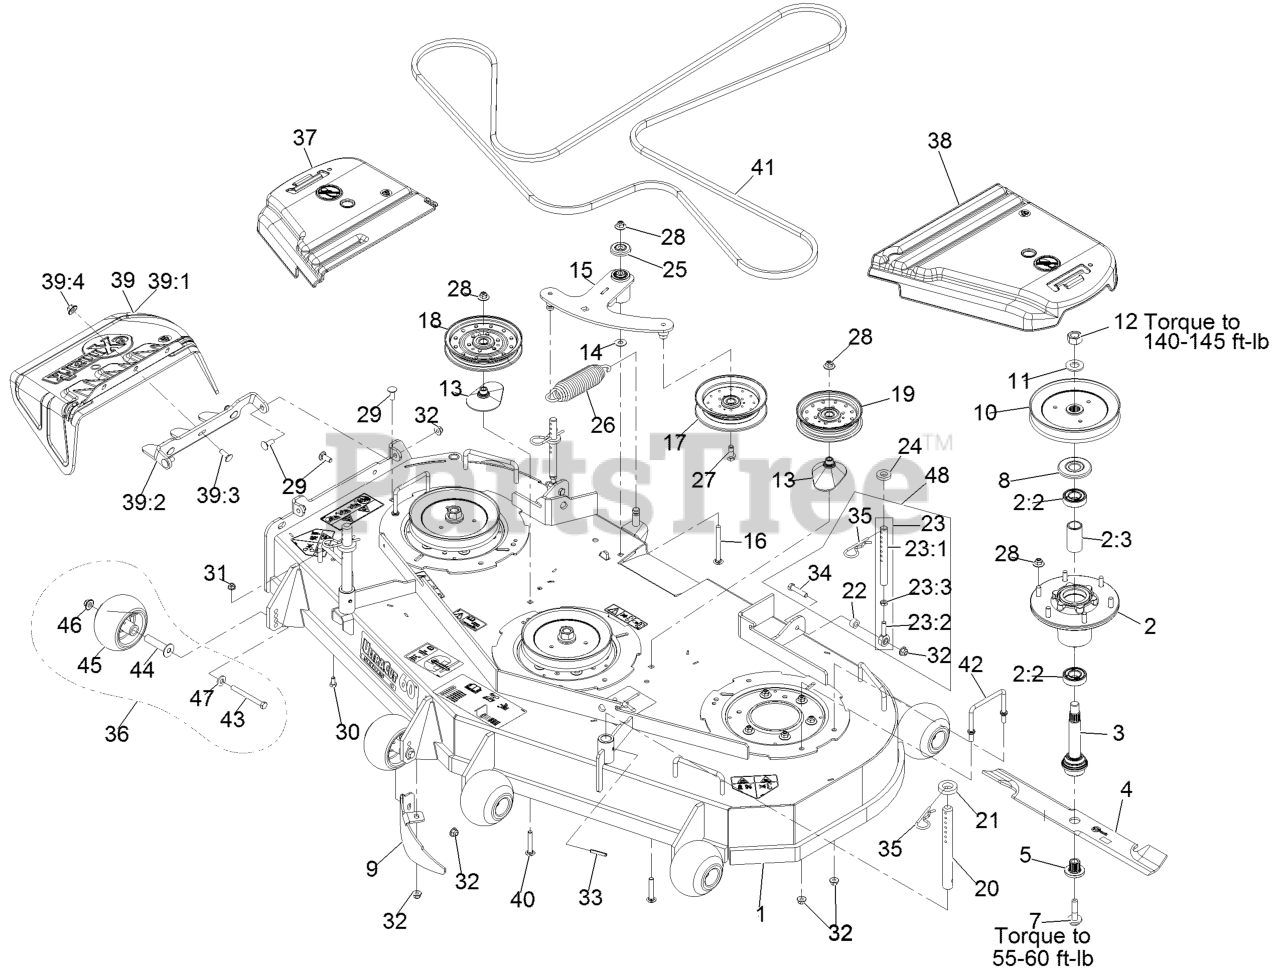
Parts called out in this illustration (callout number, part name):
1	ASM, DECK W/ DECALS, 60"
2	ASM-CUTTER HSG WITH BEARINGS
2:2	BEARING-BALL
2:3	SPACER-BEARING
3	ASM-SPINDLE AND SEAL
5	BUSHING,SPLINED
7	SCREW,SEMS 1/2-20 X 2.19
8	GUARD,BEARING TOP .989
9	DOGLEG - LZ60
10	SHEAVE,BLADE DRIVE 7.25
12	NUT-HEX
13	SPACER-PULLEY
14	WASHER-FLAT
15	ASM, DECK IDLER
16	SCREW-CARR
20	ROD,DECK SUPPORT
21	SPACER-DECK SUPPORT
23:1	LINK,SUPPORT
23:2	BALLJOINT
23:3	NUT-HJ
25	GUARD-TOP
26	SPRING-EXTENSION
27	SCREW-HFH
28	Nut-Nyloc 3/8-16 Flg
29	SCREW-CARR
30	SCREW-HH
31	NUT-HF, NI
32	NUT-HF, NI
34	SCREW-HH
35	PIN,HAIR COTTER
36	KIT, ANTI-SCALP ROLLER
37	COVER-BELT, RH
38	COVER-BELT, LH
39	ASM,DISCHARGE CHUTE
39:1	CHUTE,DISCHARGE
39:2	BRACKET,DISCHARGE CHUTE
39:3	SCREW-CARR
39:4	Nut-Nyloc 3/8-16 Flg
40	BOLT-CARR, SHORT NECK
41	BELT, DECK DRIVE
42	WIREFORM-COVER
43	SCREW-HH 3/8-16 X 3 3/4 GR 8
44	AXLE, ROLLER
45	ROLLER-SCALP, ANTI
46	Nut-Nyloc 3/8-16 Flg
47	WASHER-BELLEVILLE
48	KIT,SUPPORT LINK W/PIN
